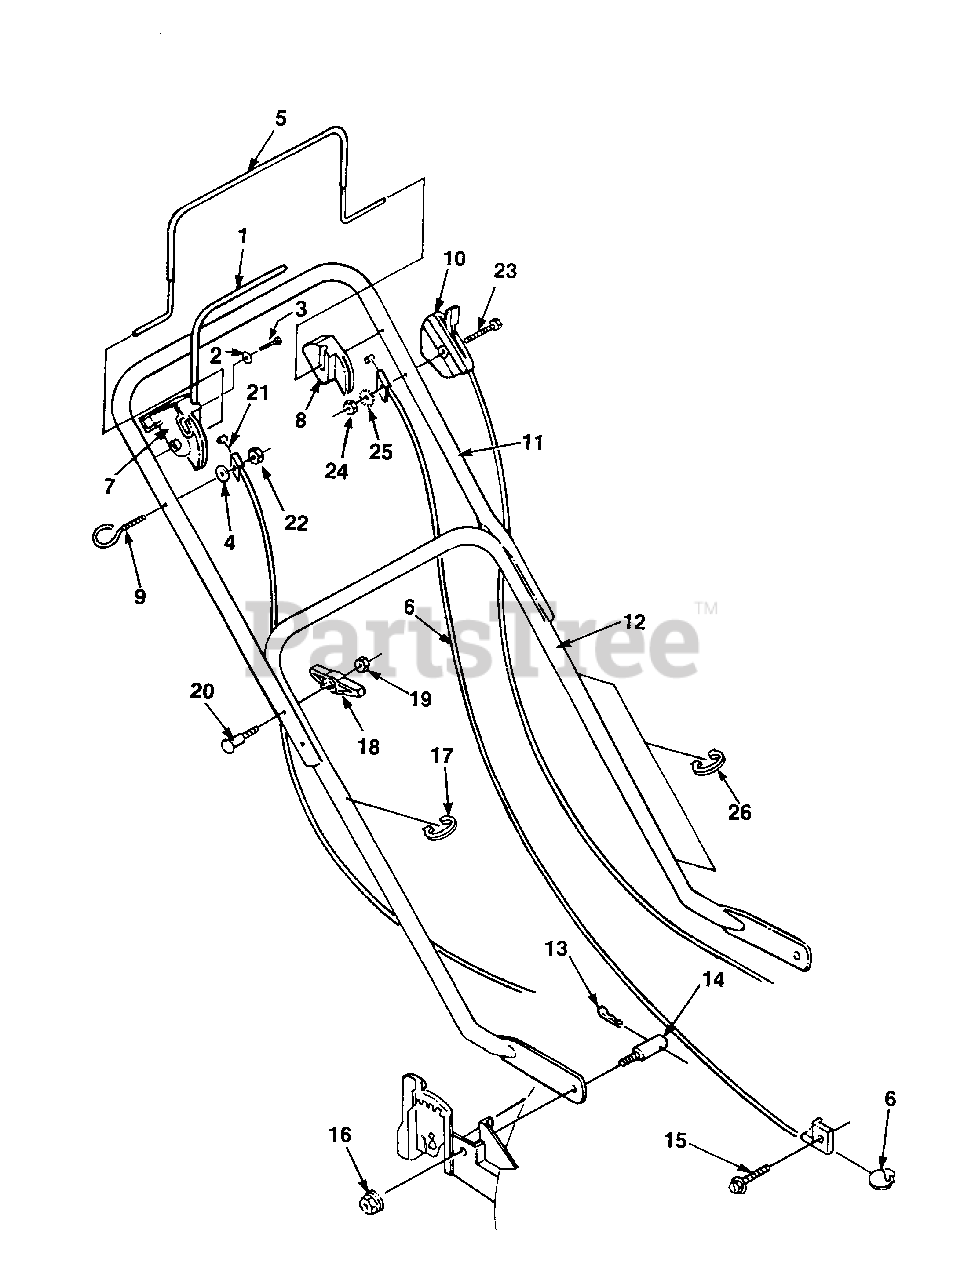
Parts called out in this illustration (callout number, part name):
1	TRACTION LEVER ASSY.
2	WASHER
3	SCREW
5	BAIL- Brake control
6	CONTROL- Manual start
7	ACTUATOR- R.H.
8	ACTUATOR- L.H.
10	CONTROL- Throttle
11	HANDLE- Upper
12	HANDLE- Lower
13	PIN- Hair
16	NUT- Flanged
17	CLAMP- Cable single
18	KNOB- Handle
19	NUT- Hex
21	CABLE- Traction control
23	BOLT- Sq. neck
24	NUT- Hex
25	WASHER- External tooth
26	CLAMP- Double
